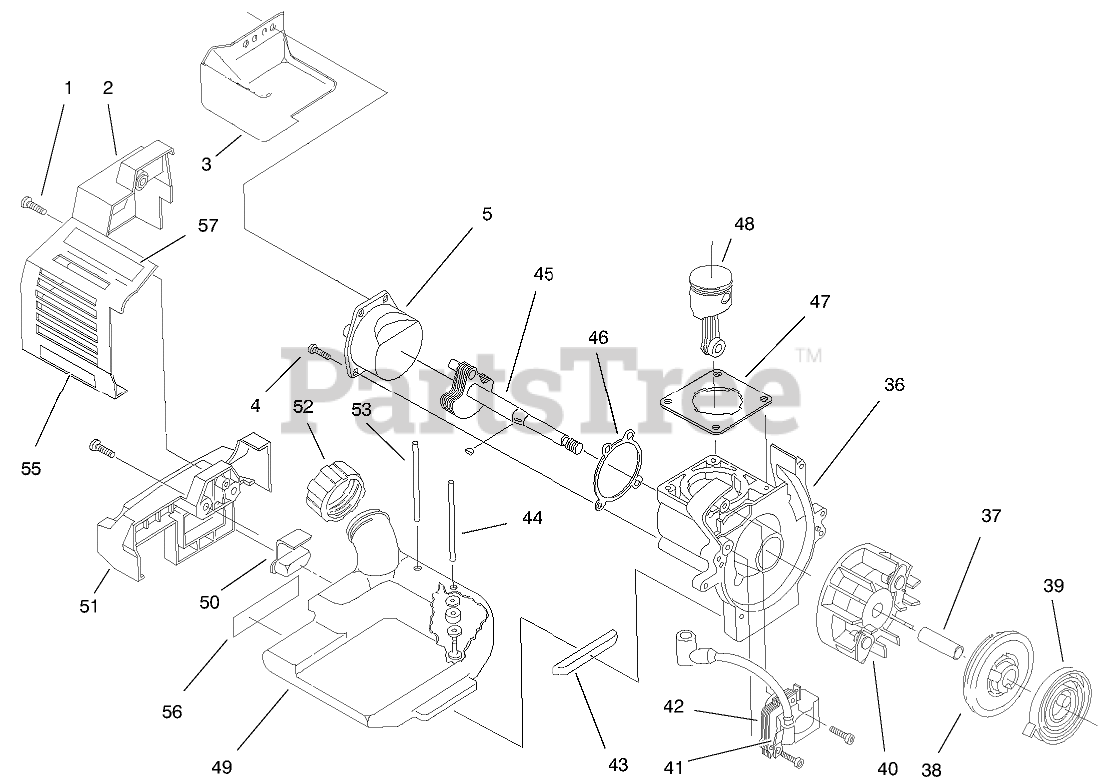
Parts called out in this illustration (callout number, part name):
1	CLUTCH COVER SCREW ASM
2	REAR COVER
3	HEAT SHIELD
4	MOUNTING SCREW SET
5	CRANKCASE CAP
36	Crankcase Asm. (Incl. Ref. # 5, 45-46)
37	SPACER
38	RECOIL PULLEY
39	RECOIL SPRING
40	FLYWHEEL
41	GROUND TAB
42	MODULE ASM
43	FRONT FUEL TANK PAD
44	FUEL LINE ASM
45	POWER SHAFT ASM
46	CRANKCASE CAP GASKET
47	CYLINDER GASKET
48	PISTON & ROD ASM
49	FUEL TANK ASM
50	REAR FUEL TANK PAD
51	FUEL TANK BRACKET
52	FUEL TANK CAP
53	FUEL RETURN LINE
55	Decal-Warning
56	Decal-Fuel & Oil Mix
57	DECAL - CARBURETOR
